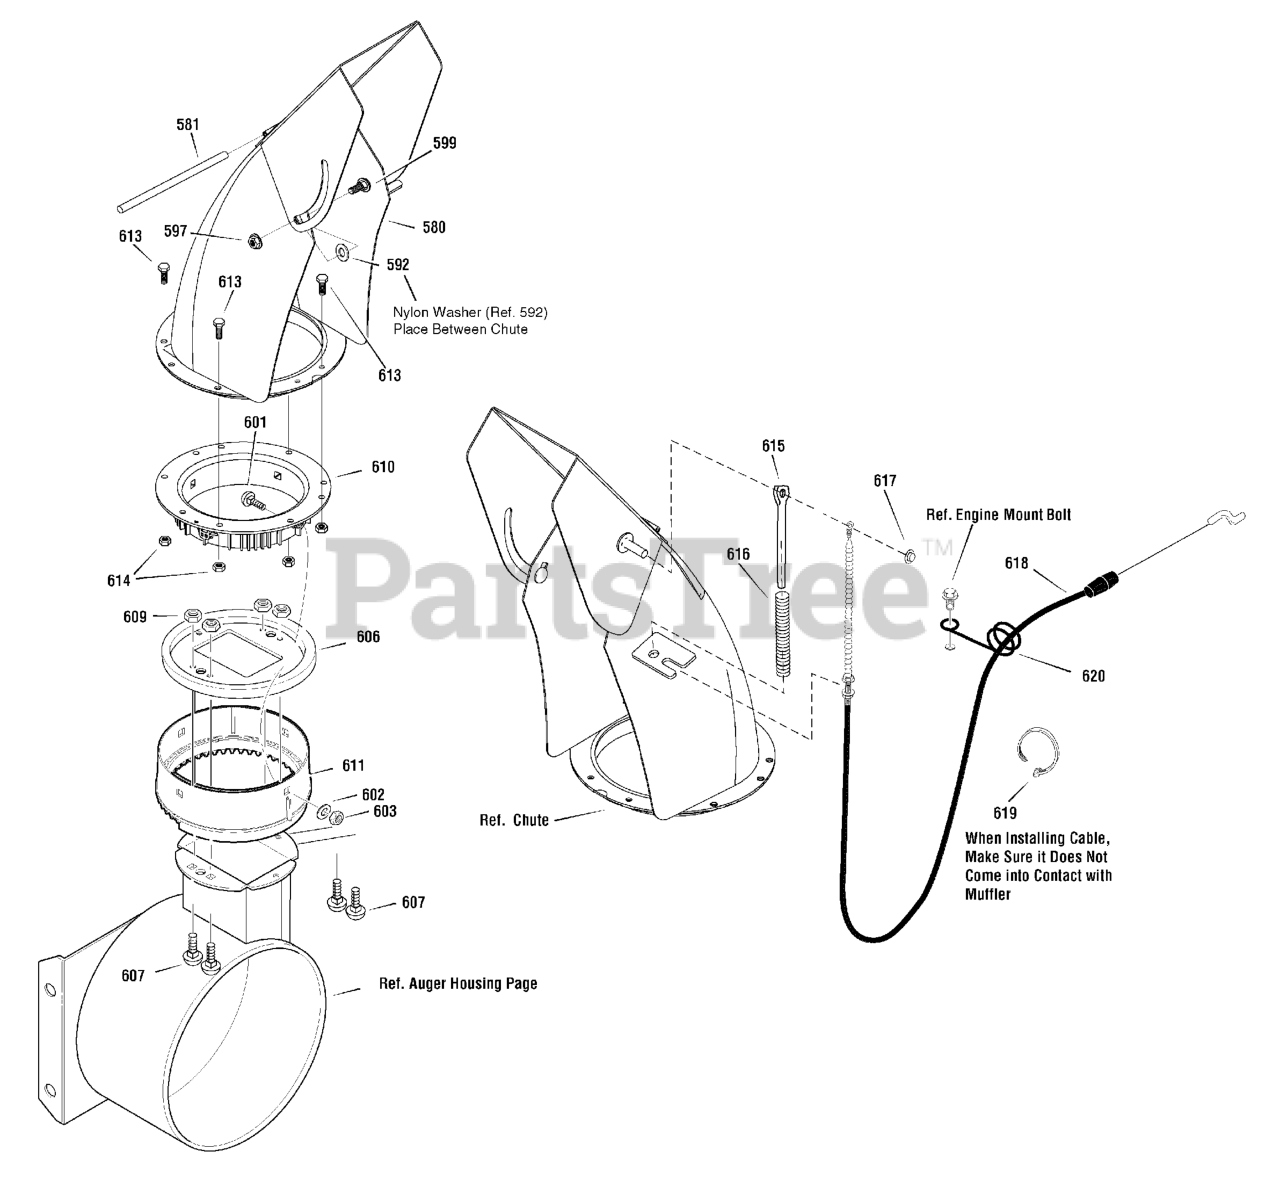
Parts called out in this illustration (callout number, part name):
580	CHUTE ASSEMBLY
581	PIN, HINGE
592	WASHER, Nylon
597	NUT, Hex-Flange, 5/16-18
599	BOLT, Carriage, 5/16-18 x 3/4
601	BOLT, 5/16-18 X 1.00
602	WASHER, Flat
603	NUT, Hex, Nylock, 5/16-18
606	CHUTE COLLAR
607	SCREW, 1/4-20 X 0.75
609	NUT, 1/4-20 Hex Nylock
610	RING, Retainer, Inner
611	RING, Retainer, Outer
613	CAPSCREW, Hex-Flange, 1/4-20 x .75
614	NUT, Flange Nylock , 1/4-20
615	ROD, Spring
616	SPRING, Compression
617	NUT, Push-Cap, 5/16
618	LEVER & CABLE, Chute Deflector
619	TIE, Cable
620	WIRE FORM, REMOTE CHUTE CABLE
